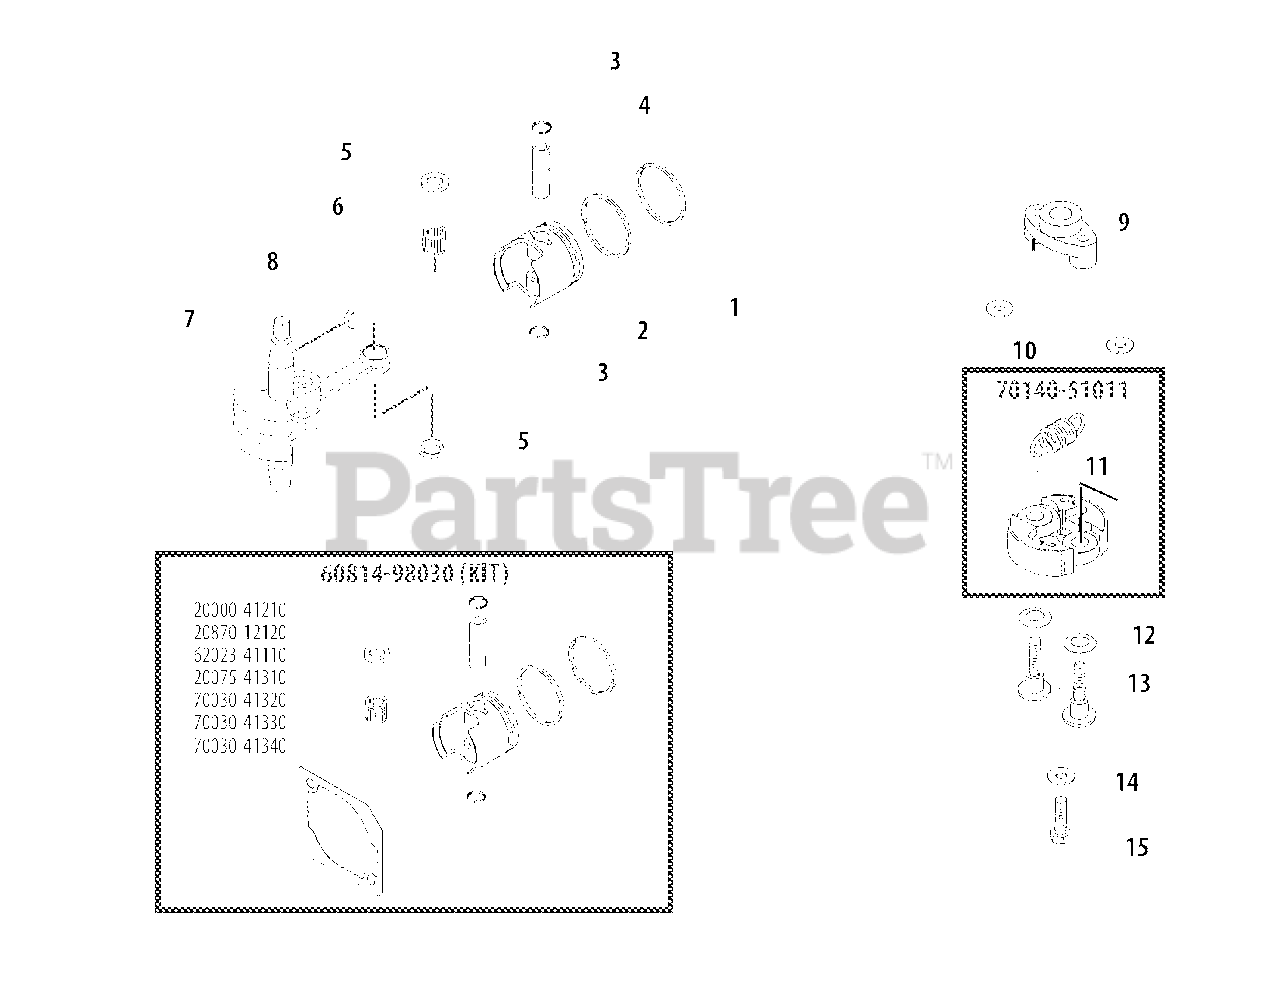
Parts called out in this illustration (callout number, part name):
1	RING, PISTON
2	PISTON
3	RING, SNAP
3	GASKET, CYLINDER
4	PIN, PISTON 8
5	WASHER, THRUST
6	BEARING, NEEDLE
7	CRANKSHAFT ASSY
8	KEY, WOODRUFF 3×10
9	HUB, CLUTCH
10	WASHER 6 MM
11	SPRING, CLUTCH
12	WASHER, SPRING
13	BOLT, CLUTCH
14	WASHER 6 MM
15	BOLT M6×18
60814-98030	PISTON ASSY
70140-51011	CLUTCH SHOE ASSY
